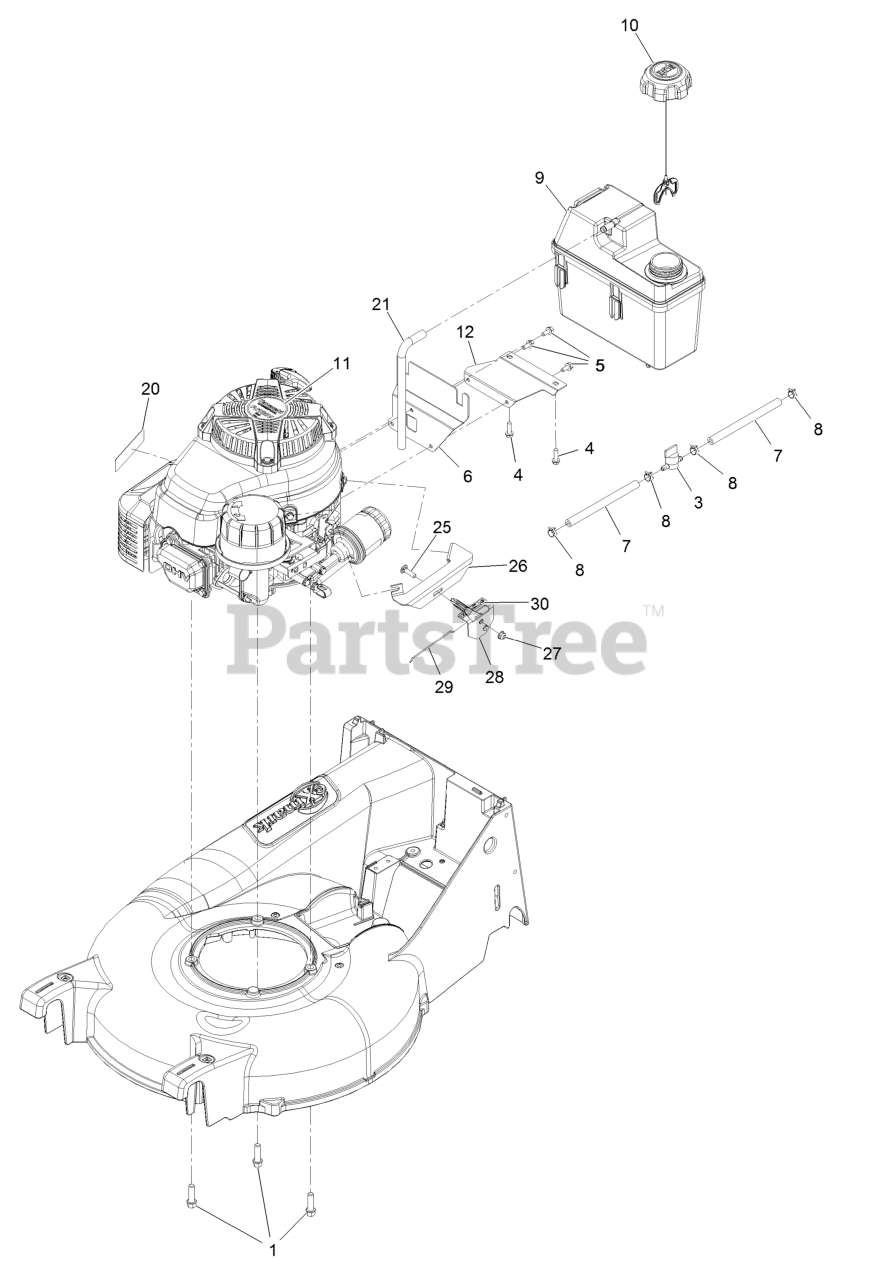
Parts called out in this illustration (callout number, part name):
1	Screw-HWH 3/8-16 X 1 1/4 Taptite
3	Valve-Fuel
4	Screw-HWH 1/4-10 X .82 Plastite
5	Screw-HWH
6	Bracket-Tank, Mounting
7	Hose-Fuel
8	Clamp-Hose
9	Tank-Fuel
10	Cap-Fuel
11	Decal-Recoil
12	Bracket-Tank, Support
20	Decal-Arrester, Spark
21	Hose-Vent, Canister
25	Bolt-Carriage 1/4-20 X 1
26	Bracket-Mount, Throttle
27	Nut-Nyloc 1/4-20 Flg
28	Control-Throttle
29	Wire-Control
30	Decal-Throttle, Choke
